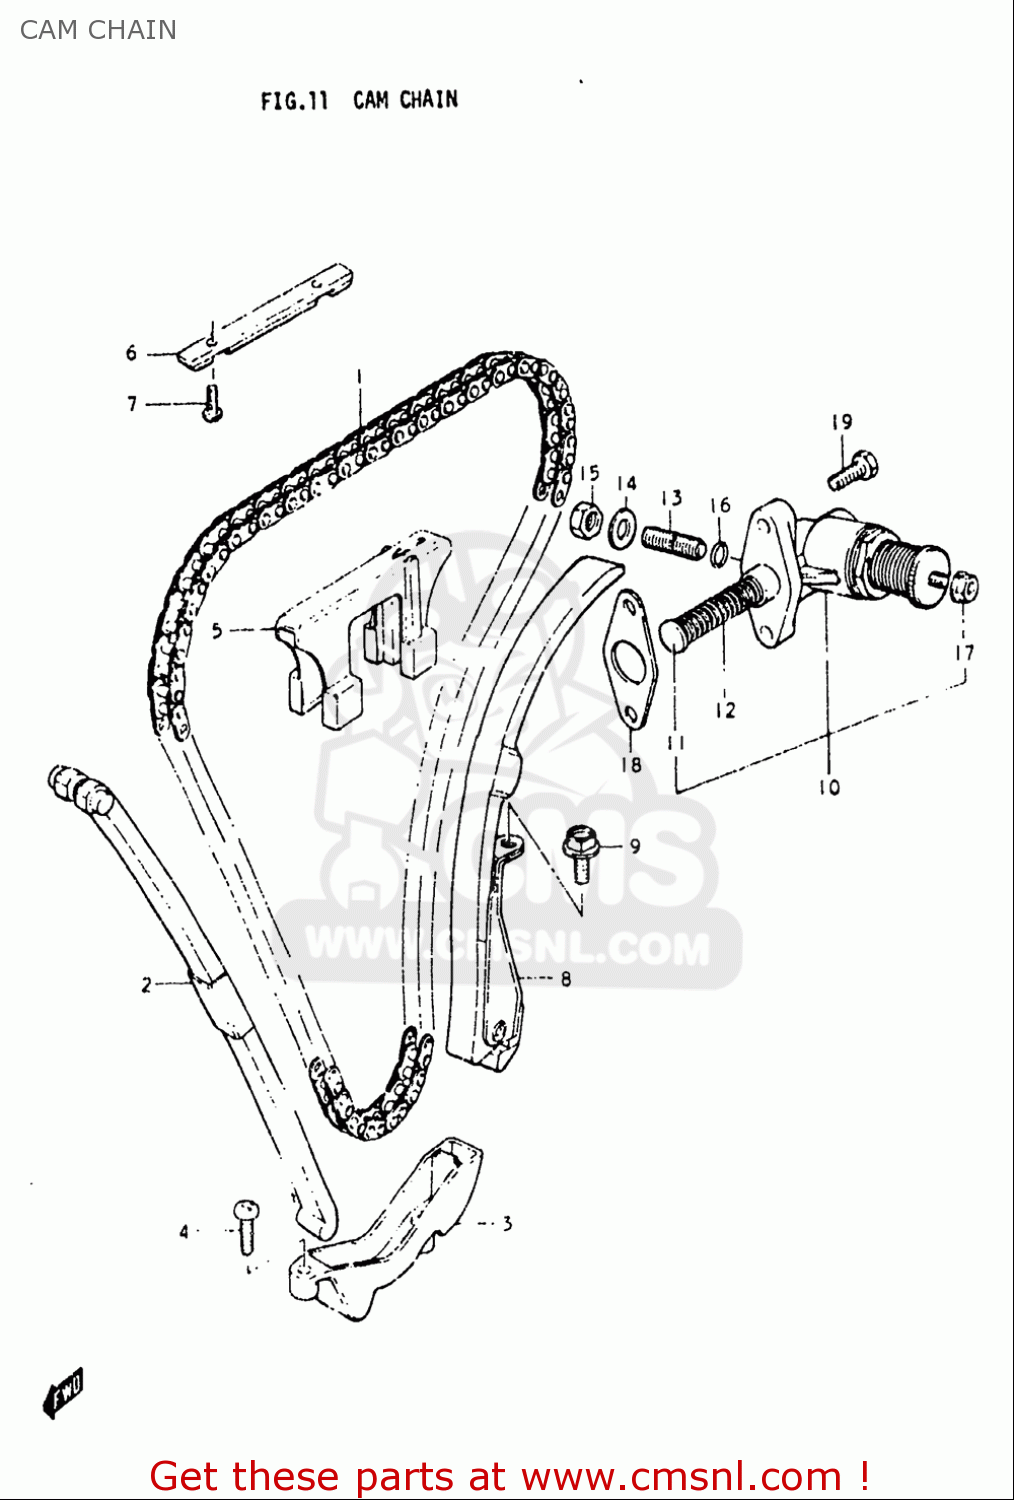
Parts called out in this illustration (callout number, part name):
1	CHAIN,CAMSHAFT DRIVE
2	GUIDE,CAM CHAIN NO.1
4	SCREW
5	GUIDE,CAM CHAIN NO.2
6	GUIDE,CAM CHAIN NO.3
7	SCREW
8	TENSIONER,CAM CHAIN
9	BOLT
11	ROD,PUSH
12	SPRING
13	SCREW
14	WASHER
15	NUT
16	O RING(D:1.9,ID:5.7)
17	NUT
18	GASKET,TENSIONER ADJUSTER (NAS)
19	SCREW (6X25)
